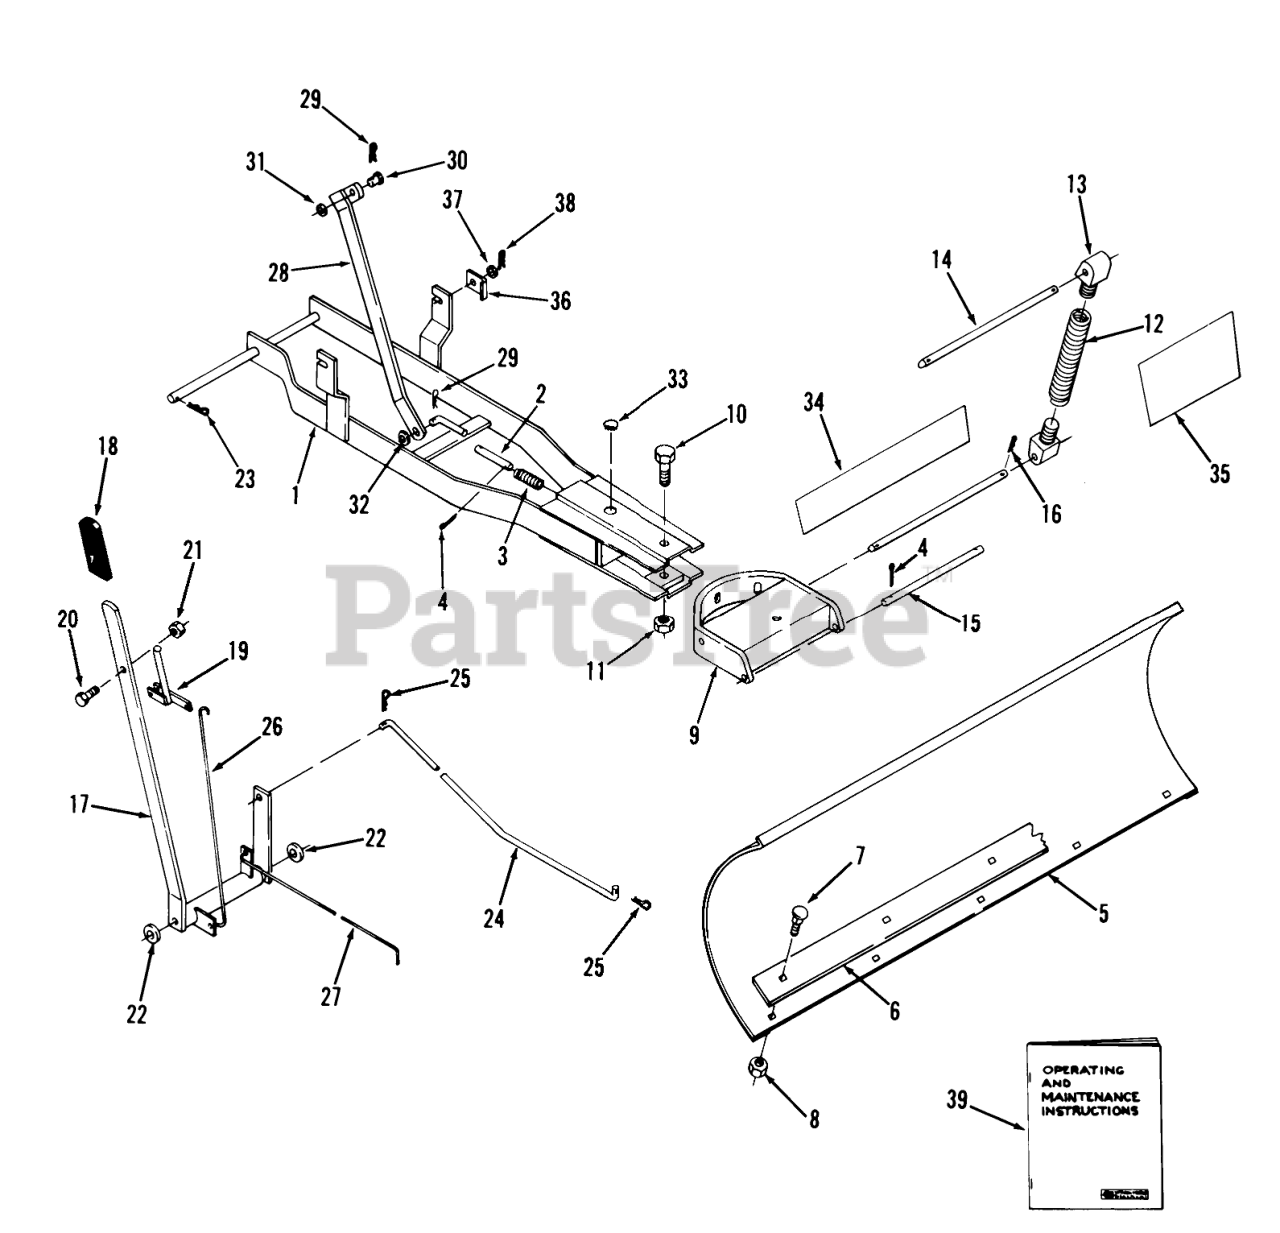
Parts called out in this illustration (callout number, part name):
1	Frame
2	Index Pin
3	SPRING-COMPRESSION
5	Blade
6	Plate
7	Bolt-Carriage
8	NUT
9	Sector and Channel
10	Bolt
11	Nut
12	Spring
13	Lug
14	ROD-PIVOT, BLADE
15	ROD-LOWER
16	Hairpin
17	Index Lever
18	GRIP
19	LEVER ASSY
20	Bolt
21	Nut
22	Washer
23	Hairpin
24	Brake Pedal
25	Hairpin
26	Upper Index Rod
27	LOWER INDEX ROD
28	Lift Bar
29	Hairpin Cotter
30	PIN
31	Washer
32	WASHER
33	PLUG
34	DECAL-WHEEL HORSE
35	Caution Decal
36	CLIP
37	Washer
38	Hairpin Cotter
39	OPERATOR MANUAL
